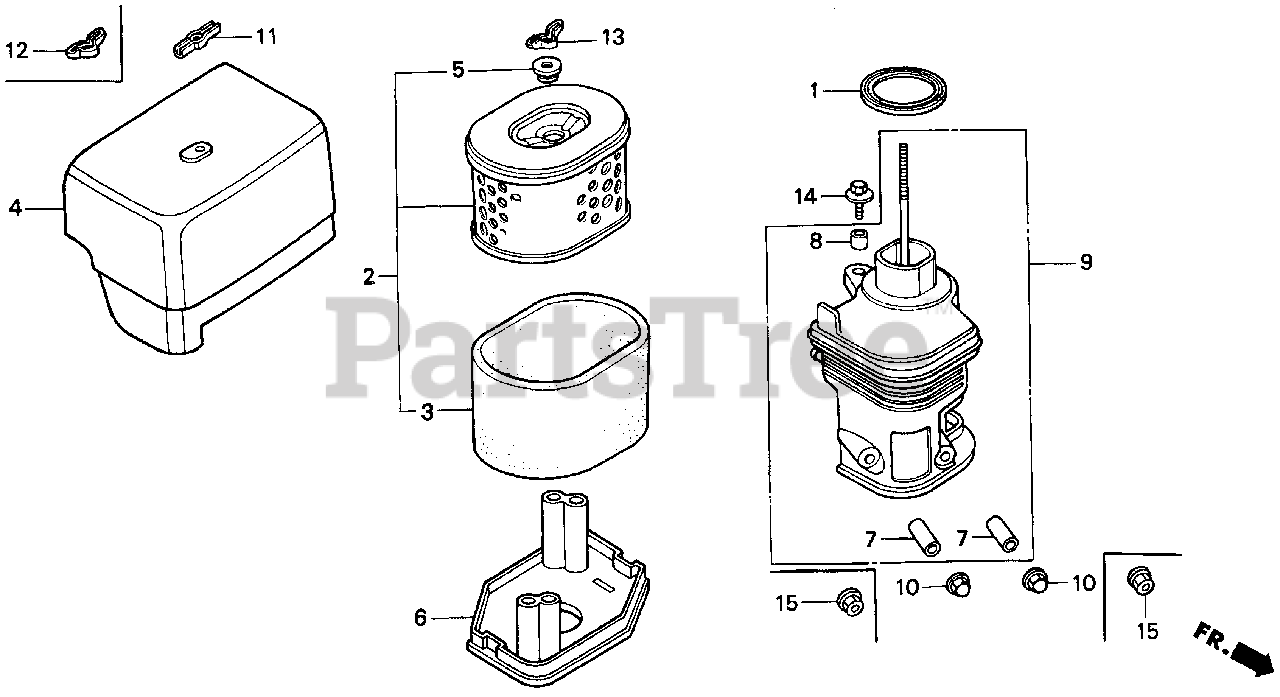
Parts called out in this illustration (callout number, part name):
1	GASKET, ELBOW
2	ELEMENT, AIR CLEANER
3	FILTER (OUTER)
4	COVER, AIR CLEANER
5	GROMMET, AIR CLEANER
6	NOSE, MUFFLER
7	COLLAR, AIR CLEANER
8	COLLAR B, AIR CLEANER
9	ELBOW, AIR CLEANER
11	WINGNUT (6MM)
12	WINGNUT, TOOL BOX SETTING
13	WINGNUT, TOOL BOX SETTING
14	BOLT-WASHER (6X20)
15	NUT, FLANGE (6MM)
